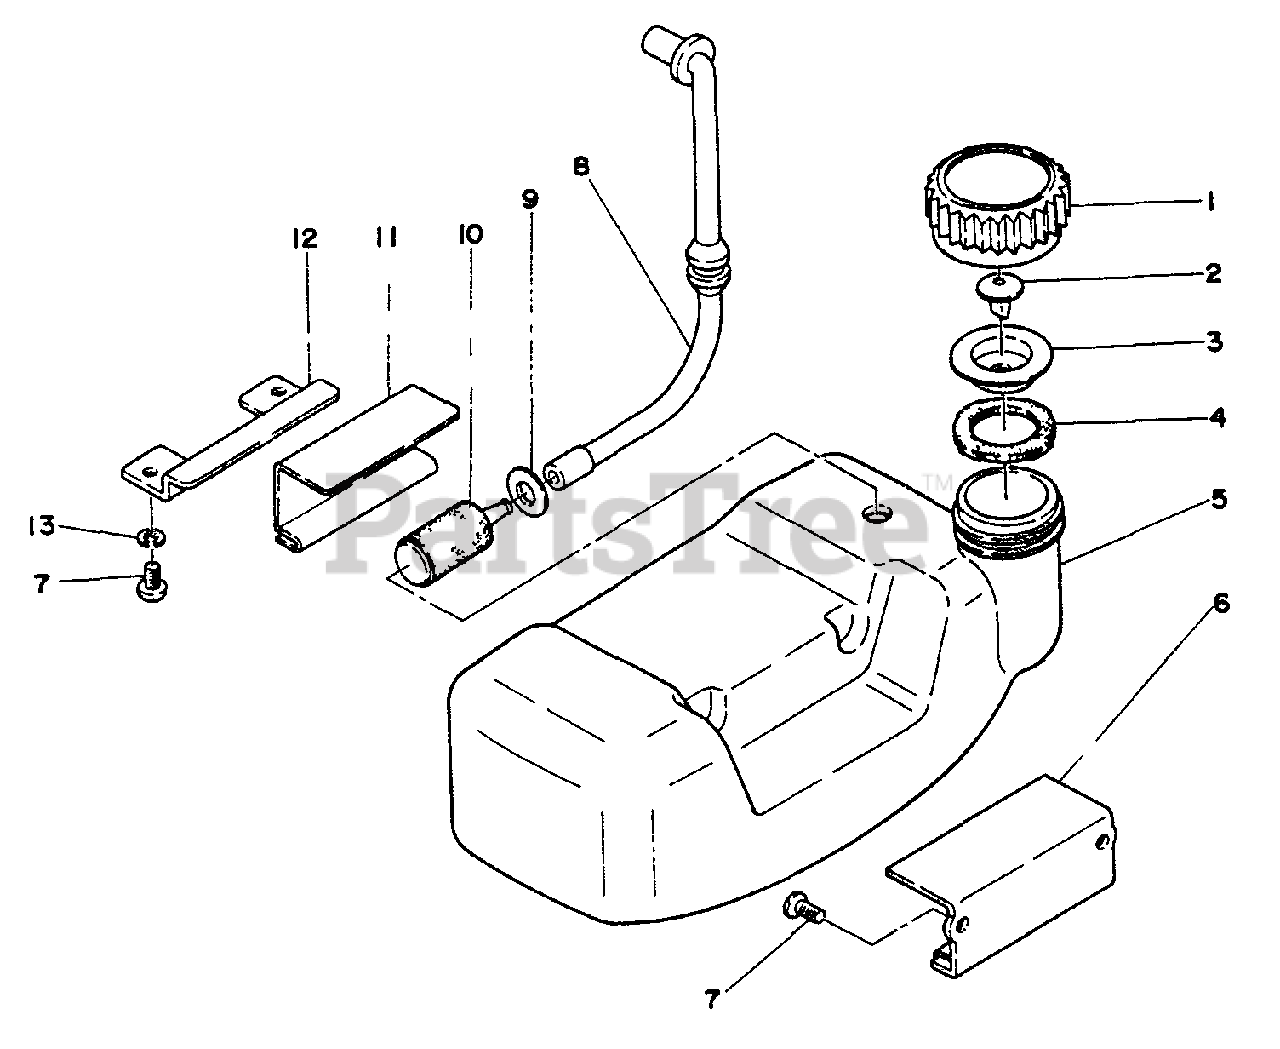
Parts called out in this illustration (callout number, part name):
1	CAP
3	HOLDER, VENT
4	GASKET, CAP
5	TANK, FUEL
6	BRACKET, FUEL TANK
7	SCREW - 4X8
8	PIPE - FUEL
9	WASHER - 6
10	FILTER, FUEL
11	CUSHION, FUEL TANK
12	BRACKET, FUEL TANK
13	LOCKWASHER - 5
